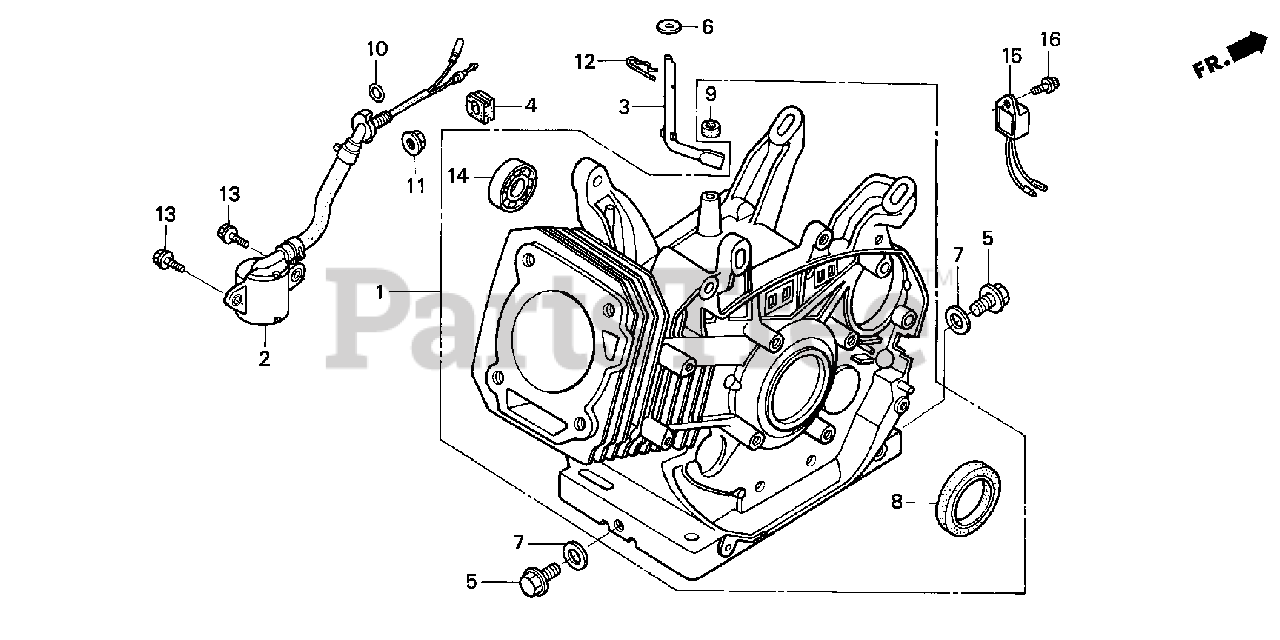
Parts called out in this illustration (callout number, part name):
1	CYLINDER ASSY. (SELFSTARTER+ALERT)
2	SWITCH ASSY., OIL LEVEL
3	SHAFT, GOVERNOR ARM
4	GROMMET, WIRE
5	BOLT, DRAIN PLUG (12X15)
5	BOLT, DRAIN PLUG
6	WASHER (8.2X17X0.8)
7	WASHER, DRAIN PLUG (12MM)
8	OIL SEAL (35X52X8)
9	OIL SEAL (8X14X5)
10	O-RING (14MM) (ARAI)
11	NUT, FLANGE (10MM)
12	PIN, LOCK (8MM)
13	BOLT, FLANGE (6X12)
14	BEARING, RADIAL BALL (6202)
